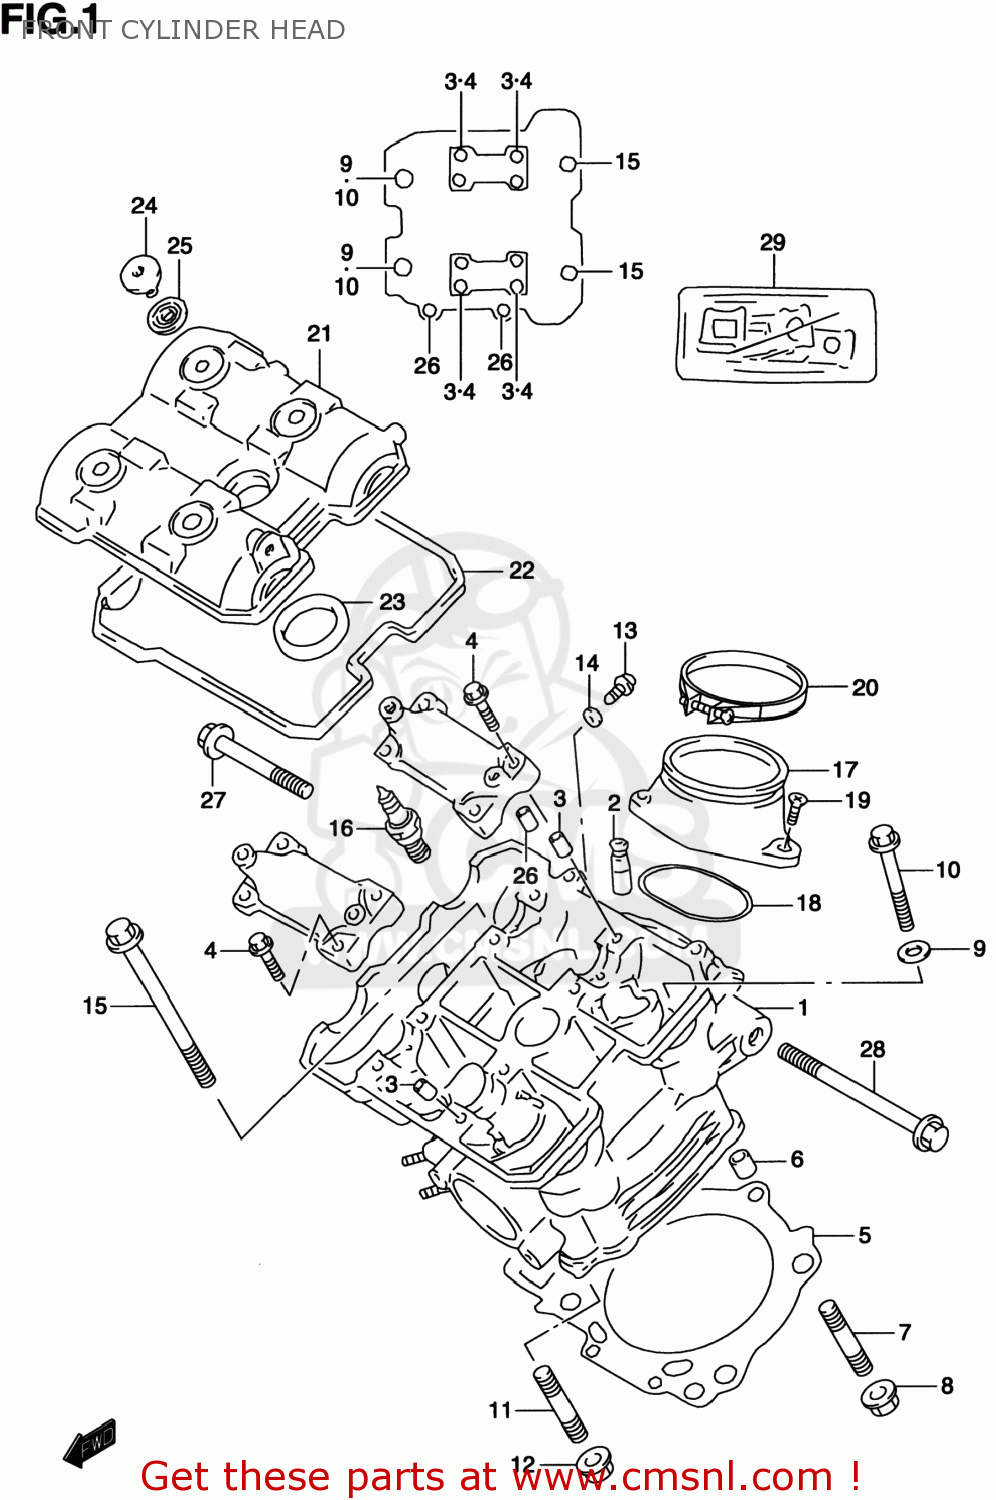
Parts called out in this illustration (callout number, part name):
1	HEAD ASSEMBLY,CYLINDER
2	GUIDE,VALVE
3	PIN(6.2X8X11)
4	BOLT(6X39)
5	GASKET,CYLINDER HEAD (NAS)
6	PIN
7	BOLT,STUD
8	NUT
9	WASHER(10.5X19X2)
10	BOLT(10X175)
11	BOLT,STUD
12	NUT
13	BOLT
14	GASKET(5.8X13X1.2) (NAS)
15	BOLT(6X70)
16	PLUG,SPARK(CR9EK)
17	PIPE ASSY,INTAKE
18	O RING(D:2.4,ID:55.6)
19	SCREW
20	CLAMP
21	COVER,CYLINDER HEAD FR
22	GASKET,CYL HEAD COVER NO.1 (NAS)
23	GASKET,CYL HEAD COVER NO.2
24	BOLT(7X17.5)
25	WASHER(10.6X25.5X2.3)
26	PIN(6.2X8X11)
27	BOLT
28	BOLT
29	GASKET SET (NAS)
30	PLUG
